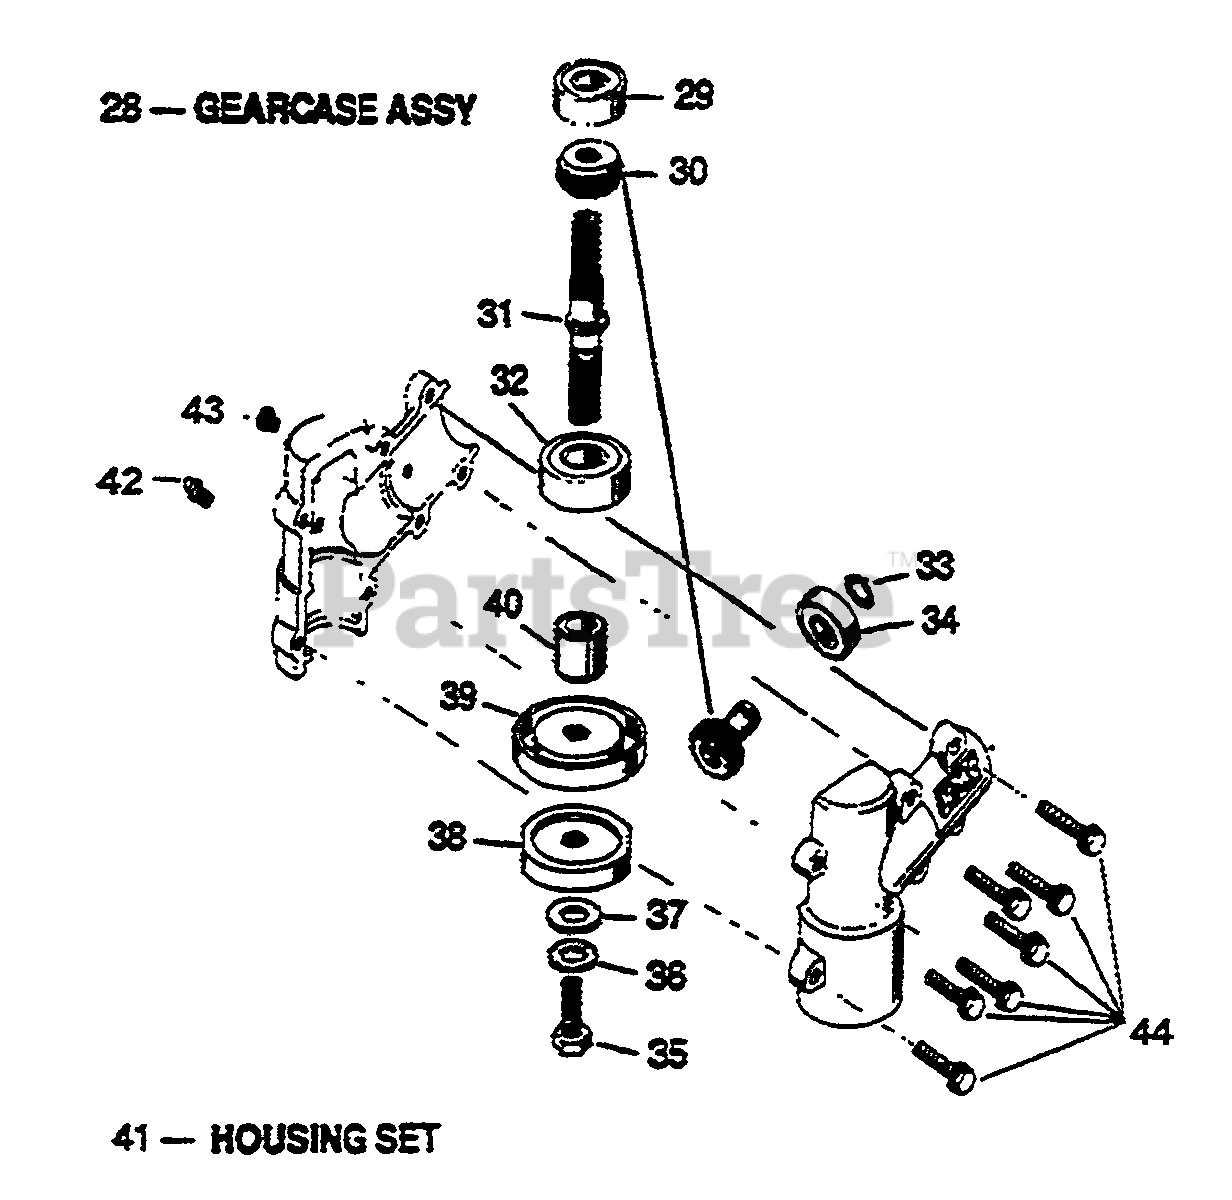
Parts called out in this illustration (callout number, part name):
28	GEARCASE ASSY
29	BEARING
30	GEAR SET KIT
31	SHAFT, GEAR
33	RING
34	BEARING
35	BOLT
36	WASHER
38	HOLDER B
41	HOUSING SET
42	FITTING ZERK
43	SCREW-SELF TAPPING
44	SCREW-SELF TAPPING
